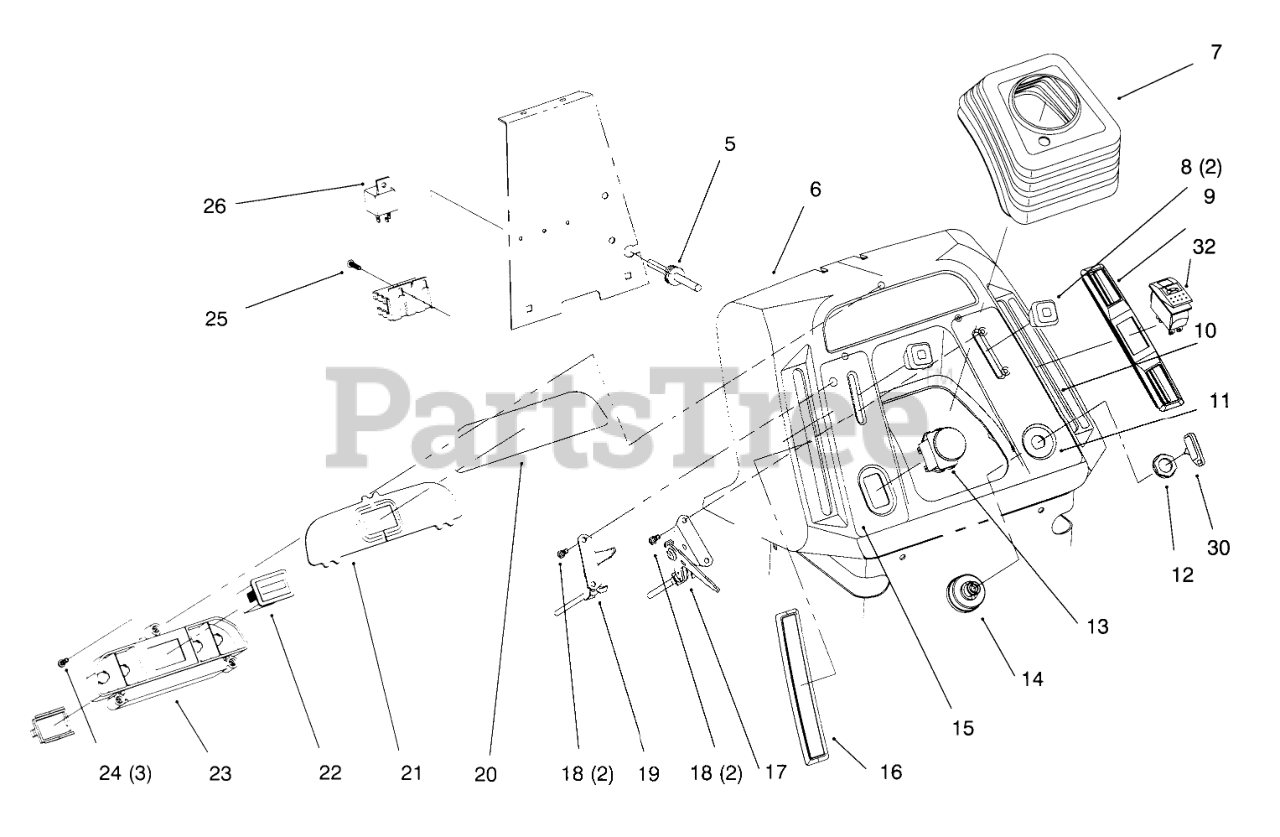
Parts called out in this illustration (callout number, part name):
5	GROMMET-RUBBER
6	DASH - HYDRO
7	BOOT-STEERING
9	COVER-SLOT, RH
11	DECAL-THROTTLE, IGNITION
13	Switch-PTO
14	SWITCH-IGNITION
15	DECAL-PTO / CHOKE
16	COVER-SLOT, LH
17	CONTROL-THROTTLE (TWIN)
19	CONTROL-CHOKE (TWIN)
20	Decal
21	LENS-DASH
22	Hourmeter
23	4 LIGHT HOUSING
24	SCREW-PPH
25	SCREW-PPHTF
26	RELAY
30	KEY-IGNITION
32	SWITCH-CRUISE
